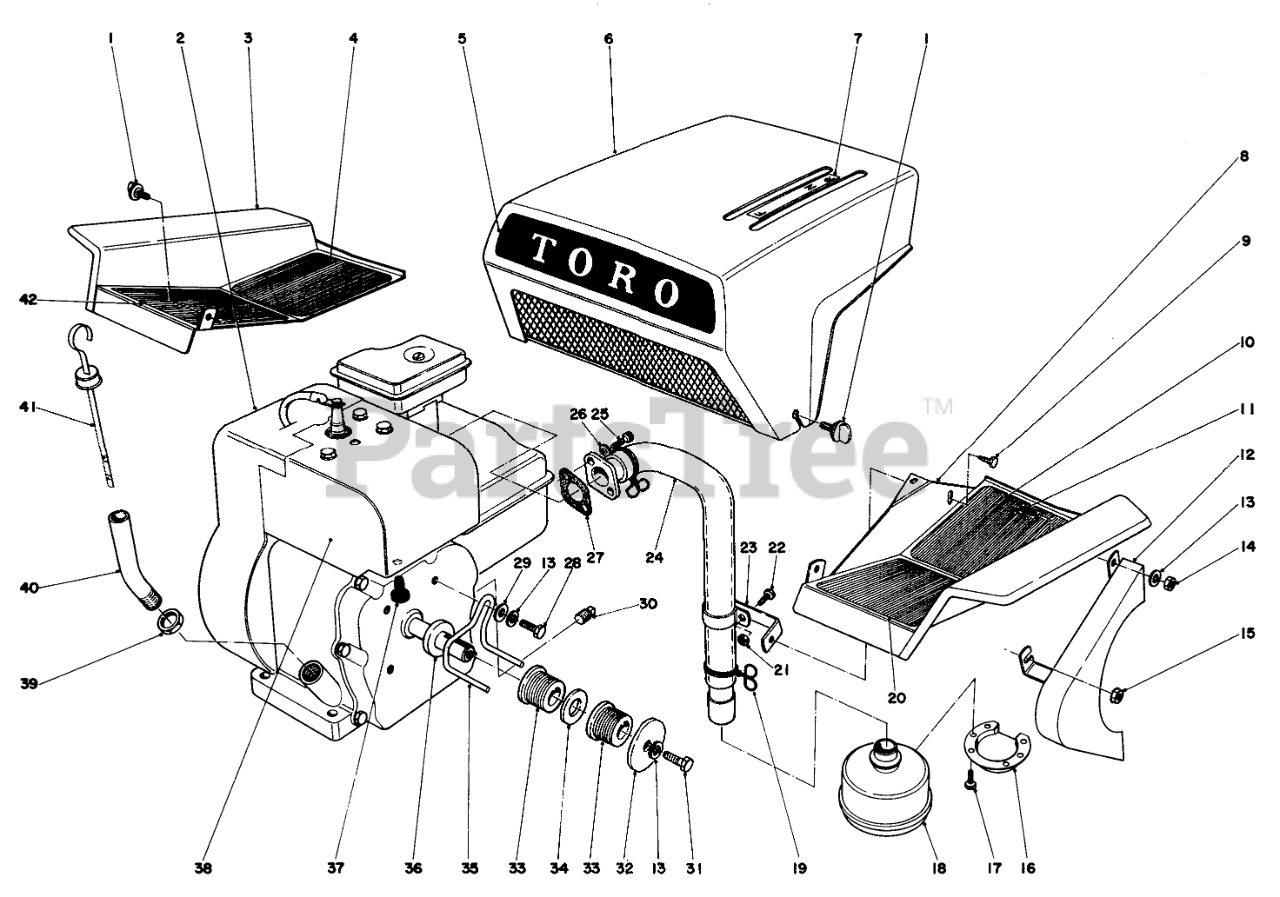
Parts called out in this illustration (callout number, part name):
1	THUMB SCREW WA
2	Engine
3	Fender (Incl. Ref. #4 & 42)
4	Pad, Foot Rest
5	NAME PLATE DECAL
6	Shroud
7	Decal
8	Fender & Insulation (Incl. Ref. #10 & 20)
9	10-16 X 3/8 THDG SCREW
10	Pad, Foot Rest
12	Chain Guard
13	WASHER-LOCK
14	NUT-HEX
15	NUT-KEPS
16	Deflector
17	SCREW W/ENGINE
18	Muffler
19	Bale Tie
20	Pad, Foot Rest
21	NUT-HEX, SIDE DEFORM
22	SCREW-HH
23	Bracket, Muffler Support
24	Exhaust Pipe Assembly (Incl. Ref. #19)
25	SCREW-HSH
26	WASHER-LOCK
27	Gasket
28	SCREW-HH
29	WASHER-PLAIN
30	PLUG-PIPE, SQH
31	SCREW-HH
32	Washer
33	Pulley, Engine Reel
34	WASHER-THRUST
35	Guide
36	Washer
37	BUMPER-RUBBER
38	Deflector
39	PAL NUT
40	Extension Oil Fill
41	DIPSTICK ASM R
42	Pad Foot Rest
